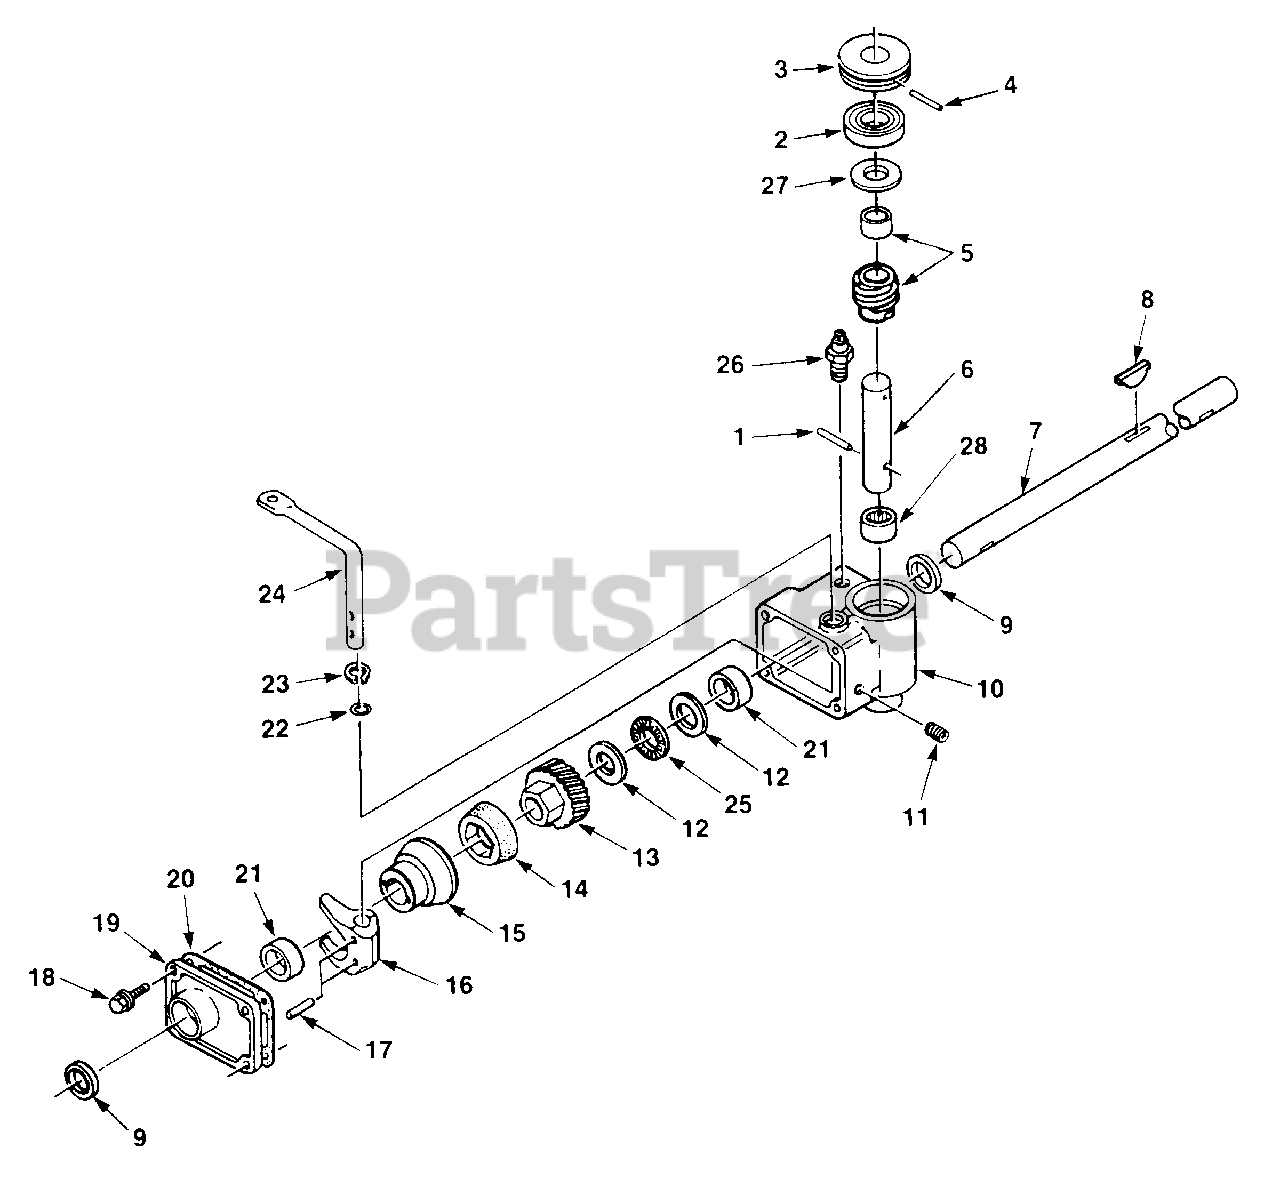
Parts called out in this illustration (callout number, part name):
3	PULLEY
5	WORM & SPACER
6	SHAFT- Worm
7	SHAFT- Drive
10	GEAR REDUCER HOUSING ASSY.
12	RACE- Bearing
13	GEAR- Helical
14	CONE- Friction
15	DRUM- Clutch
16	FORK- Shift
19	COVER- Gearbox
20	GASKET
21	BUSHING- Sleeve
24	LEVER- Shift
25	BEARING- Thrust
28	BEARING- Needle
